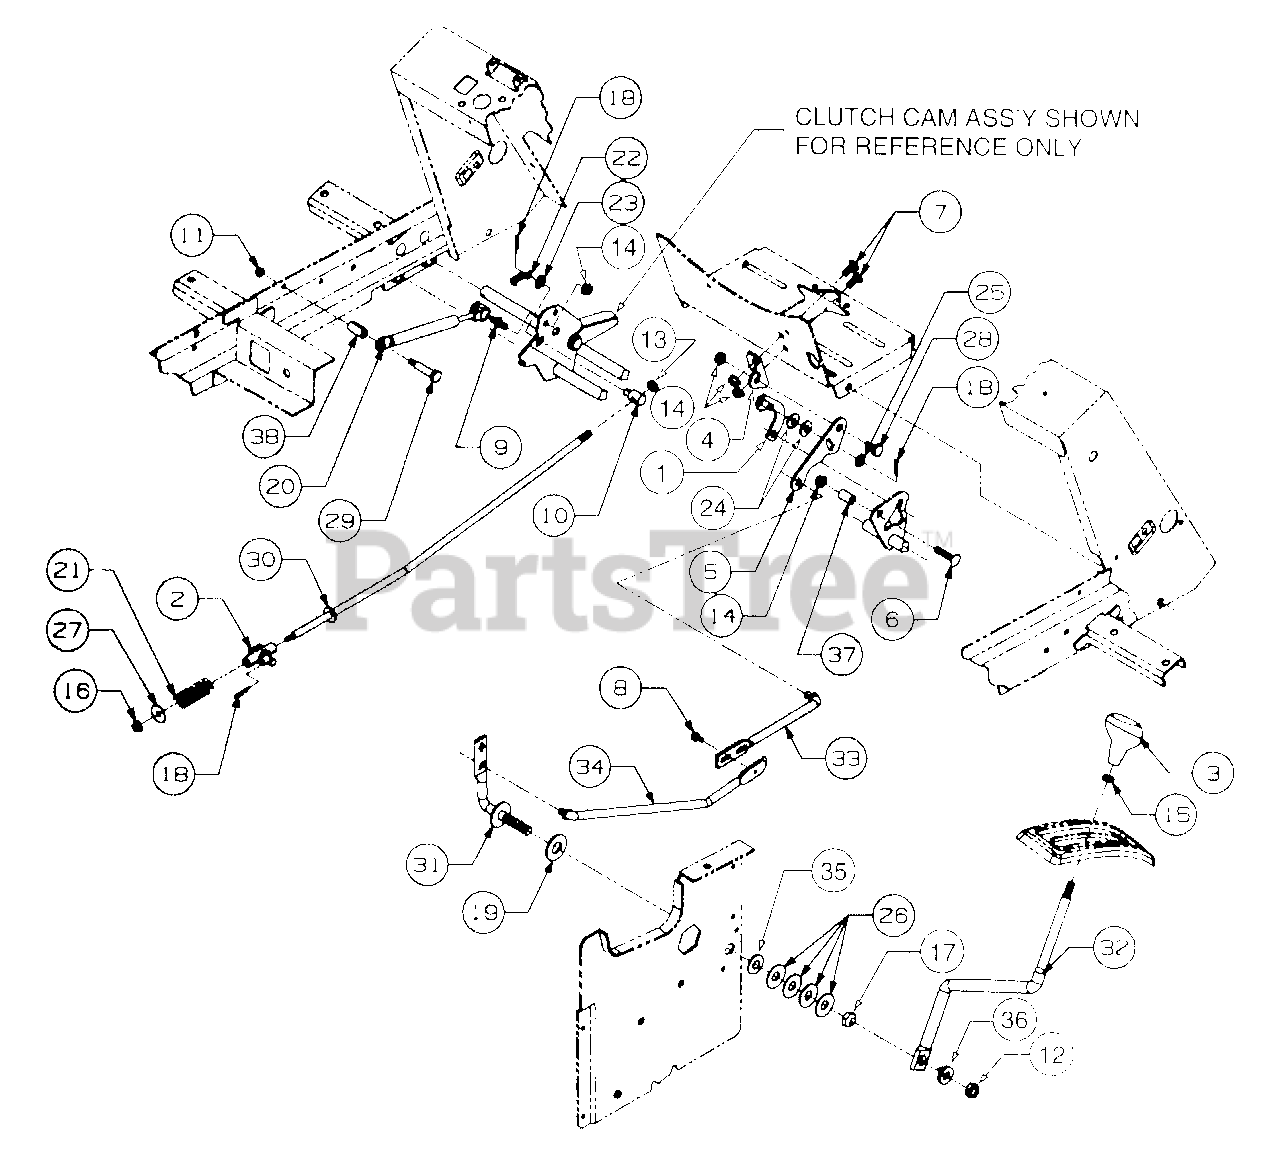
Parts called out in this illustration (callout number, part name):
1	Bracket, Cruise Return
2	Pivot Assy, Sleeve
3	Knob, Shifter
6	Bolt, Carriage, 5/16-18 x 1.5
7	Bolt, Carriage, 5/16-18 x .75
8	Screw, Hex Wash Hd Tapp 1/4-20 x .50
9	Screw, Ball, 5/16-18
10	Ferrule, Adjustment
11	Nut, Hex Sems, 1/4-20
12	Nut, Hex Top Lock, 1/2-20
13	Nut, Hex Jam, 3/8-24 GR5
14	Nut, Hex Flange Lock, 5/16-18
15	Nut, Hex Jam, 3/8-16 GR5
16	Nut, Hex Flange Lock, 1/4-20
17	Nut, Hex, 1/2-20
18	Pin, Internal Cotter
19	Washer, Friction
20	Cylinder, Damper
21	Spring, Compression, .63 ID x 2.0
22	Spring, Extension, .38 OD x 1.44
23	Washer, Flat, .406 x .75 x .063
24	Washer, Flat, .375 x .870 x .090
25	Washer, Flat, 5/16
26	Washer, Bell
27	Washer, Flat, .265 x 1.0 x .03 Hd
28	Bolt, Shoulder, .437 Dia x .180 Lg
29	Bolt, Shoulder, .347 Dia x 1.375
30	Rod, Hydro Adjustment
31	Rod, Shift
32	Rod, Gear Selector
33	Link, Front Hydro Shifter
34	Link, Rear Hydro Shifter
35	Bushing, Shoulder
36	Hub, Shift
37	Spacer, .377 ID x .50 OD x .830
38	Spacer, Tubing, .375 x .52 x 1.04
